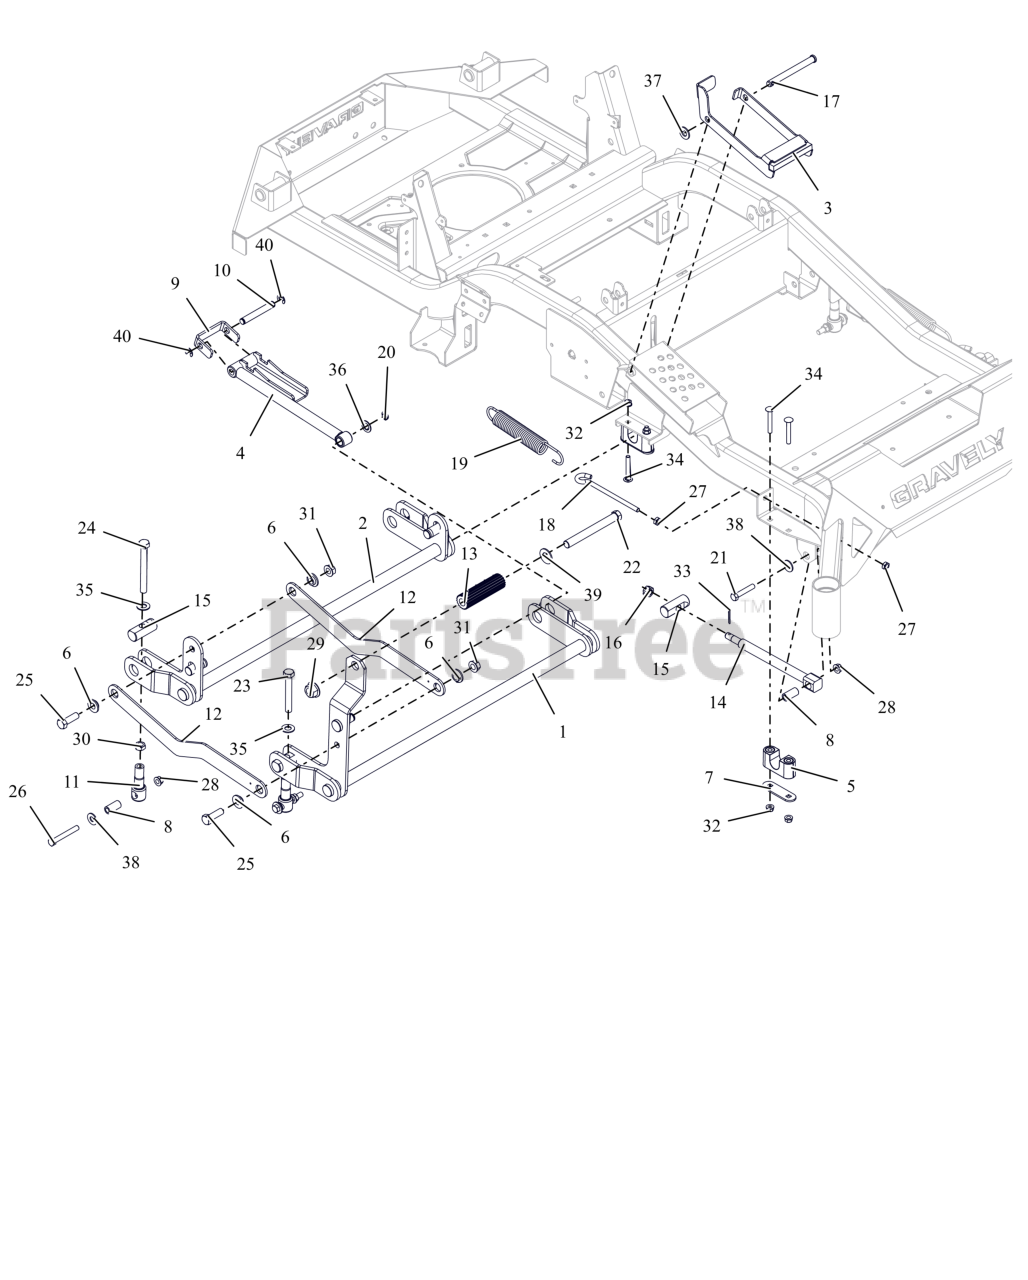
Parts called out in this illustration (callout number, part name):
1	WLDMT, FRONT DECK LIFT PIVOT
2	WLDMT, REAR DECK LIFT PIVOT
3	BRKT, HOC TRANSFER LOCK
4	WLDMT, HOC ARM
5	ASM-BUSHING, DECK LIFT
6	BSHG-FLG .515X.750X.310X1.120
7	PLATE, BEARING SUPPORT
8	SPACER, DECK LEVELING
9	BRKT, HOC LINE
10	ROD, HOC PIVOT
11	LINK, DECK LIFT FORMED
12	LINK, DECK LIFT
13	ROD, FOOT PEDAL (BLACK)
14	DRAG,LINK-HD
15	PIN, DECK LIFT
16	NUT-SL .50-13
17	PIN, SLIC-.500X4.97X4.55 -ZC
18	BOLT,.38-16 X 5.25-.62 DIA EYE
19	SG-TENS .162X1.25X8.25 WLD 25
20	RG-RTNG-EXT .625X.050
21	BLT,HEX .38-16X2.00 G5 ZCC
22	BLT, HEX .62-11X5.50 G5 FBP
23	BLT, HEX 0.5-13X3.5F GR5 ZCC
24	BLT, HEX .50-13X4.50F G8 ZCC
25	BLT,HEX .50-13X1.50 G5 ZCC
26	BLT, HEX .38-16X2.75 G8 ZCC
27	NUT-JAM .375-16 G2 ZCC
28	NUT-LK-TOP-FLG .38-16 ZC120
29	NUT,FLG-TOP LK .625-11 FBP
30	NUT-JAM .500-13 G2 ZCC
31	NUT-LK-TOP-FLG .500-13 GF ZCC
32	NUT,LK-CTR-FLG .31-18 GF ZCC
33	PIN,CTR.12X1.25EXTPRSQCT ZC120
34	BLT, RHSSN.31-18X2.25 G5 ZCC
35	WSHR, FLT .557X1.040X.102 ZCC
36	WSHR, FLT .630X1.005X.062 ZCC
37	WSHR,FLT .531X1.062X.095 ZCC
38	WSHR,FLT .438X1.00X.083 ZCC
39	WSHRFLT 5/8SAE CARBHARD FBP
40	RG-RTNG-EXT .500X.042 (E)
